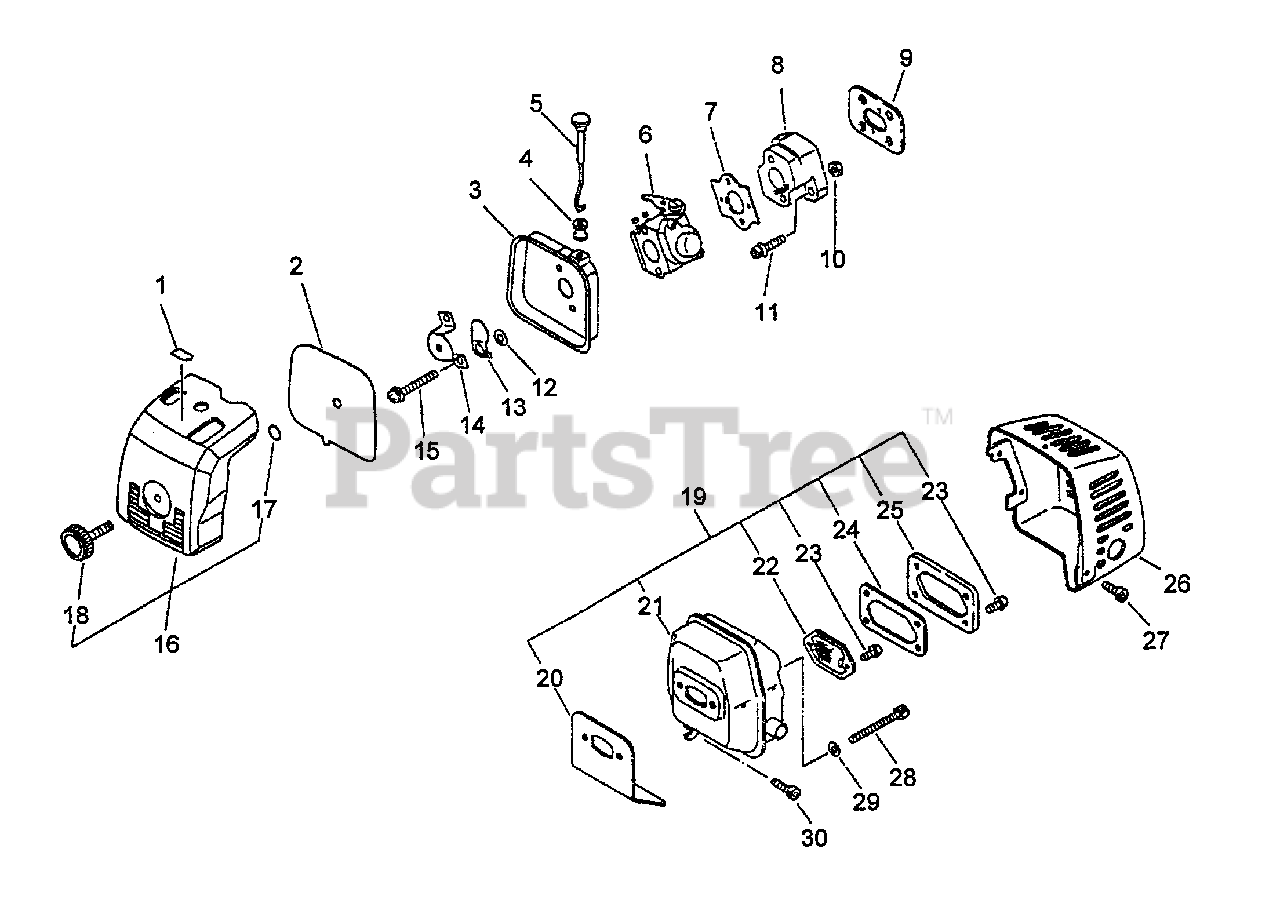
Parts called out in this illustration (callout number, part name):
1	LABEL - CHOKE
2	FILTER, AIR - HEAVY DUTY
3	CASE, AIR FILTER
5	ROD, CHOKE
6	CARBURETOR WT-333
7	GASKET, INTAKE
8	INSULATOR, INTAKE
9	GASKET, INTAKE
11	SCREW - 5X25
12	WASHER - 5
13	SHUTTER, CHOKE
14	PLATE, PREVENT
15	SCREW - 5X57
16	AIR FILTER COVER ASSY
17	O-RING - 3
18	THUMBSCREW
19	MUFFLER ASSY
20	GASKET, EXHAUST
21	MUFFLER
22	SCREEN, SPARK ARRESTOR
23	SCREW - 4X10
24	GASKET, EXHAUST
25	GUIDE, EXHAUST
26	COVER, MUFFLER
27	SCREW - 5X14
28	SCREW - 5X60
29	WASHER - 5
30	SCREW - 5X12
